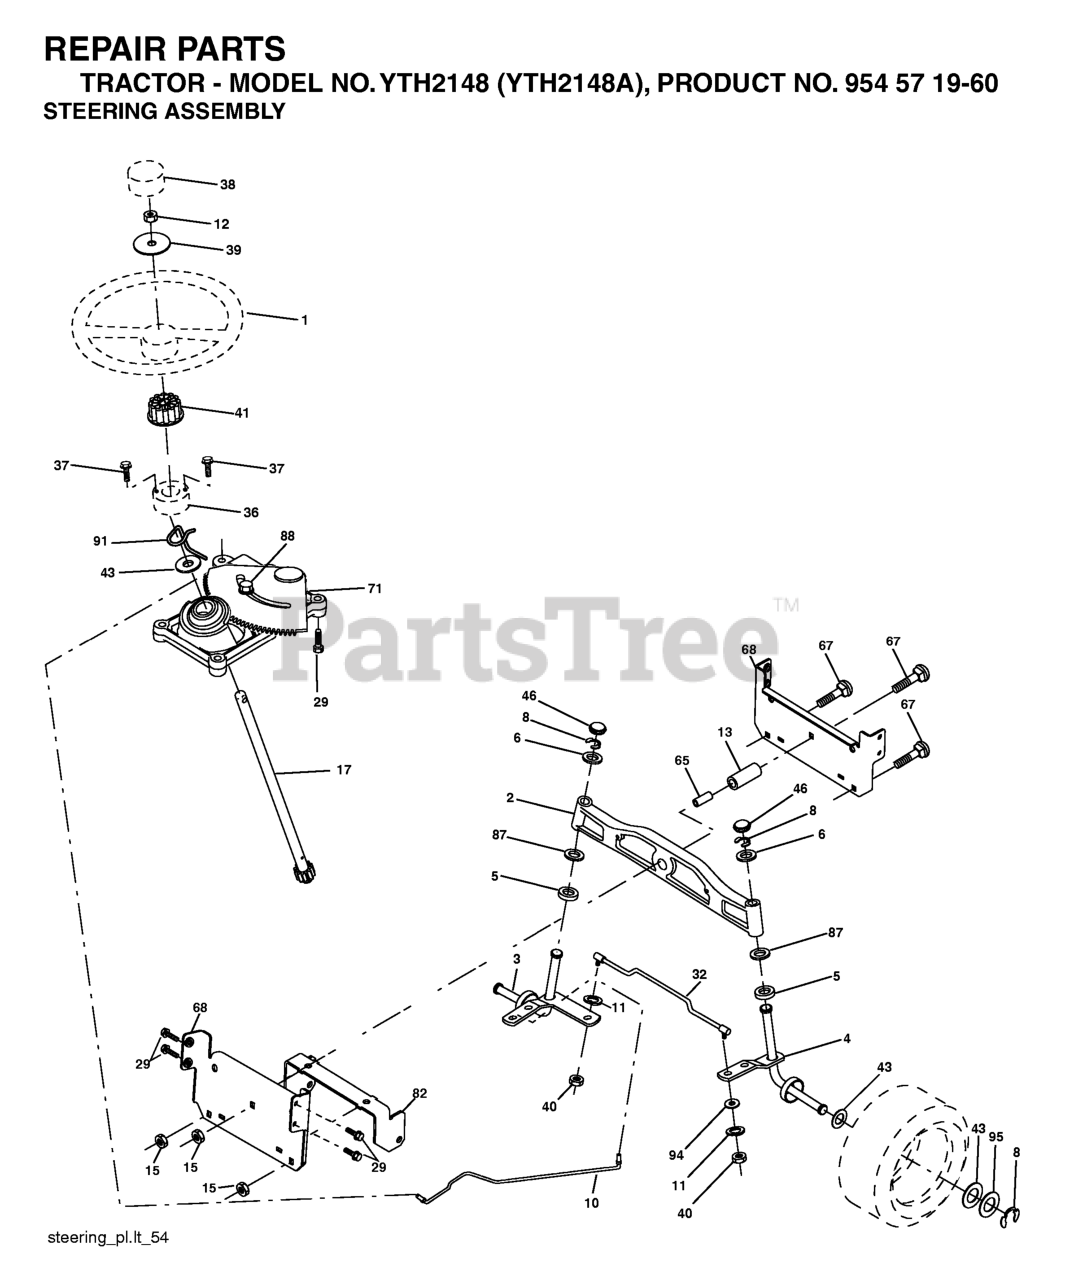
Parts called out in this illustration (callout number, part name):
1	STEERING WHEEL
2	AXLE ASSY FRONT
3	SPINDLE.ASM.LH.15"TIRES
4	SPINDLE.ASM.RH.15"TIRES
5	THRUST WASHER
10	DRAGLINK.15".TIRES.2001
11	WASHER, LOCK 3/8
12	NUT.HEX.1/2-20
13	TUBE, PIVOT AXLE
15	NUT
17	SHAFT ASM STRG
29	SCREW, 3/8-16X3/4
32	ROD TIE BALL J WSL
34	WASHER.LOCK.HVY.HLCL.SPR.5/16
36	BUSHING, STRG. BLK
37	SCREW.TT.#10-32X.5.3/8.FLANGE
38	CAP.WHEEL.STEERING.GREY
39	WASHER 9/16"ID, 2 3/8"OD
40	NUT CROWNLOCK 3/8-24
41	STEERING WHEEL ADAPTOR
46	CAP.SPINDLE.BLACK
65	SPACER BRACE AXLE
67	BOLT CARRIAGE
68	BRACE.AXLE.15"TIRES
71	STEERING ASM
82	BRACKET
87	WASHER, FLAT .781 X 1 1/2"
88	BOLT, SHOULDER 7/16-20
91	CLIP.STEERING
94	WASHER.5/16.FLAT.STE.STD.
95	WASHER.HARDENED
